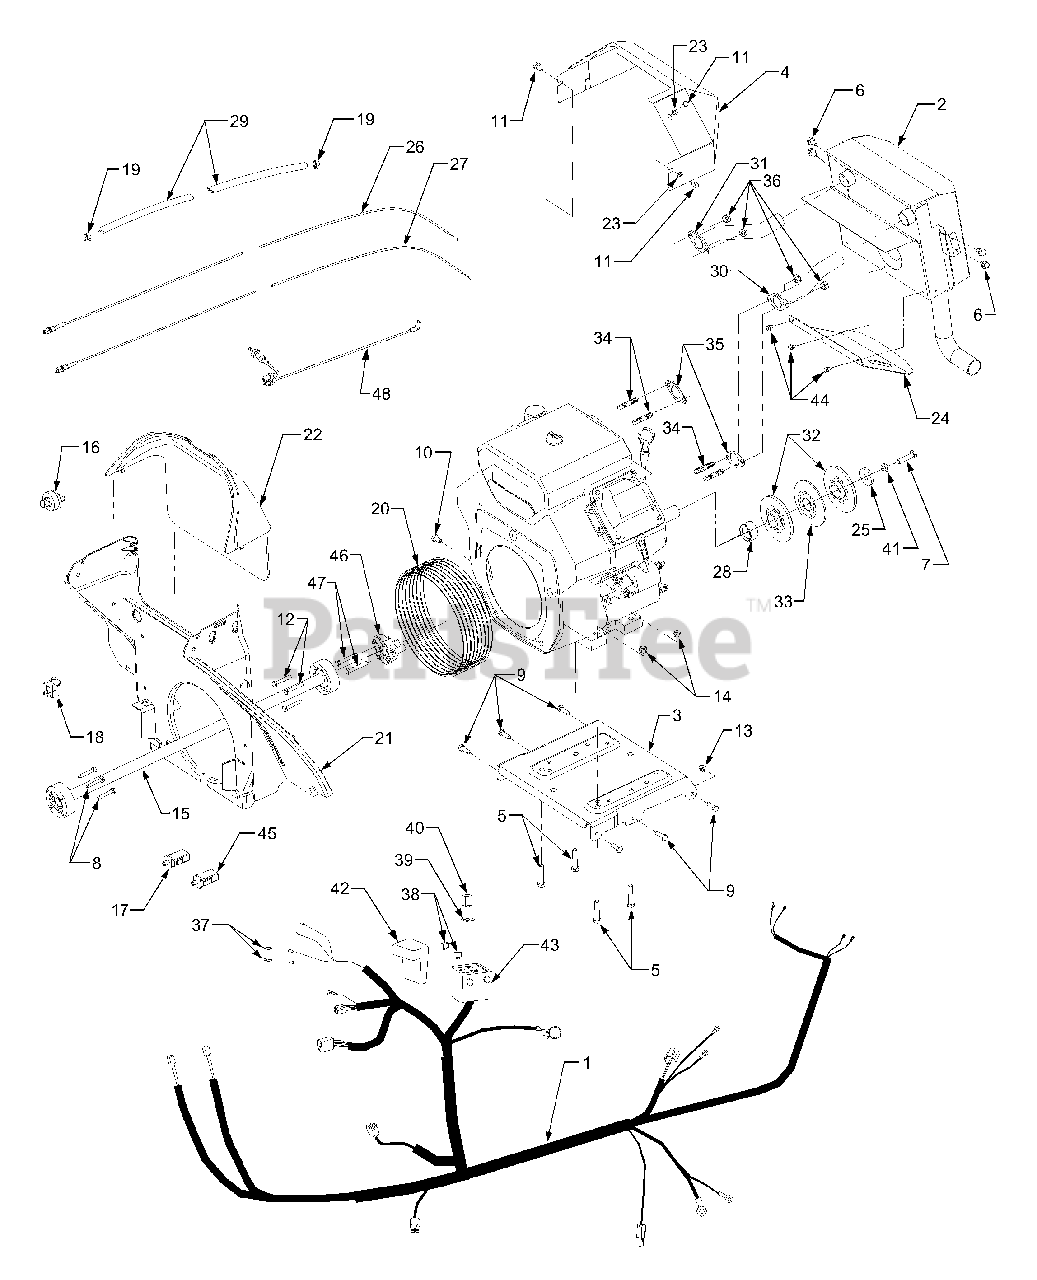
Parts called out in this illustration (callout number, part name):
1	Harness, Wire
1	Tie, Pushmount
1	Clip, Cable
2	Muffler Assembly
3	Plate, Engine Mounting
4	Shield, Muffler Heat
5	Screw, Hex Cap, 3/8-24 x 1.75 GR5
6	Screw, Hex Wash. Hd. Tapp 5/16-18 x .5
7	Screw, Hex Cap, 7/16-20 x 1.5 GR5
8	Screw, Hex Cap Lock 1/4-20 x 1.25 GR5
9	Screw, Hex Cap, 5/16-18 x .875 GR5
10	Screw, Hex Cap, 5/16-24 x .625 GR5
11	Screw, Hex Cap, M6 - 1.0 x 10MM
12	Screw, Hex Cap, Lock 1/4-20 x 1.62 GR5
13	Nut, Hex Insert Lock, 5/16-18
14	Nut, Hex Lock, 3/8-24
15	Shaft, Drive, 27.125 Long
16	Switch, Key, w/Groung
17	Switch, Plunger (Reverse)
18	Switch, Snap Mount (Seat)
19	Clamp, Hose
20	Boot, Intake
21	Baffle, Lower Air
22	Baffle, Upper Air
23	Washer, Flat, .281 x .50 x .06
24	Shield, Lower Exhaust
25	Washer, Flat, .417 x 1.5 x .225
26	Cable, Throttle Control
27	Cable, Choke Control
28	Spacer, Crankshaft
29	Hose, Fuel Line
30	Pipe, Exhaust RH
31	Pipe, Exhaust LH
32	Pulley Half
33	Pulley, Center
34	Stud, M8 - 1.25 x 33MM
35	Gasket, Exhaust
36	Nut, Hex, M8 x 1.25
37	Bulb, Indicator
38	Fuse, 25 Amp
39	Gasket, Silicone
40	Relay
41	Washer, Lock, 7/16
42	Cover, Fuse Box
43	Box, Fuse
44	Screw, Hex Wash. Hd. Tapp, #12-24 x .38
45	Switch, Plunger (Brake)
46	Adapter, Drive Shaft
47	Screw, Hex Flange, M10 x 1.5 x 90
48	Hose, Vacuum
